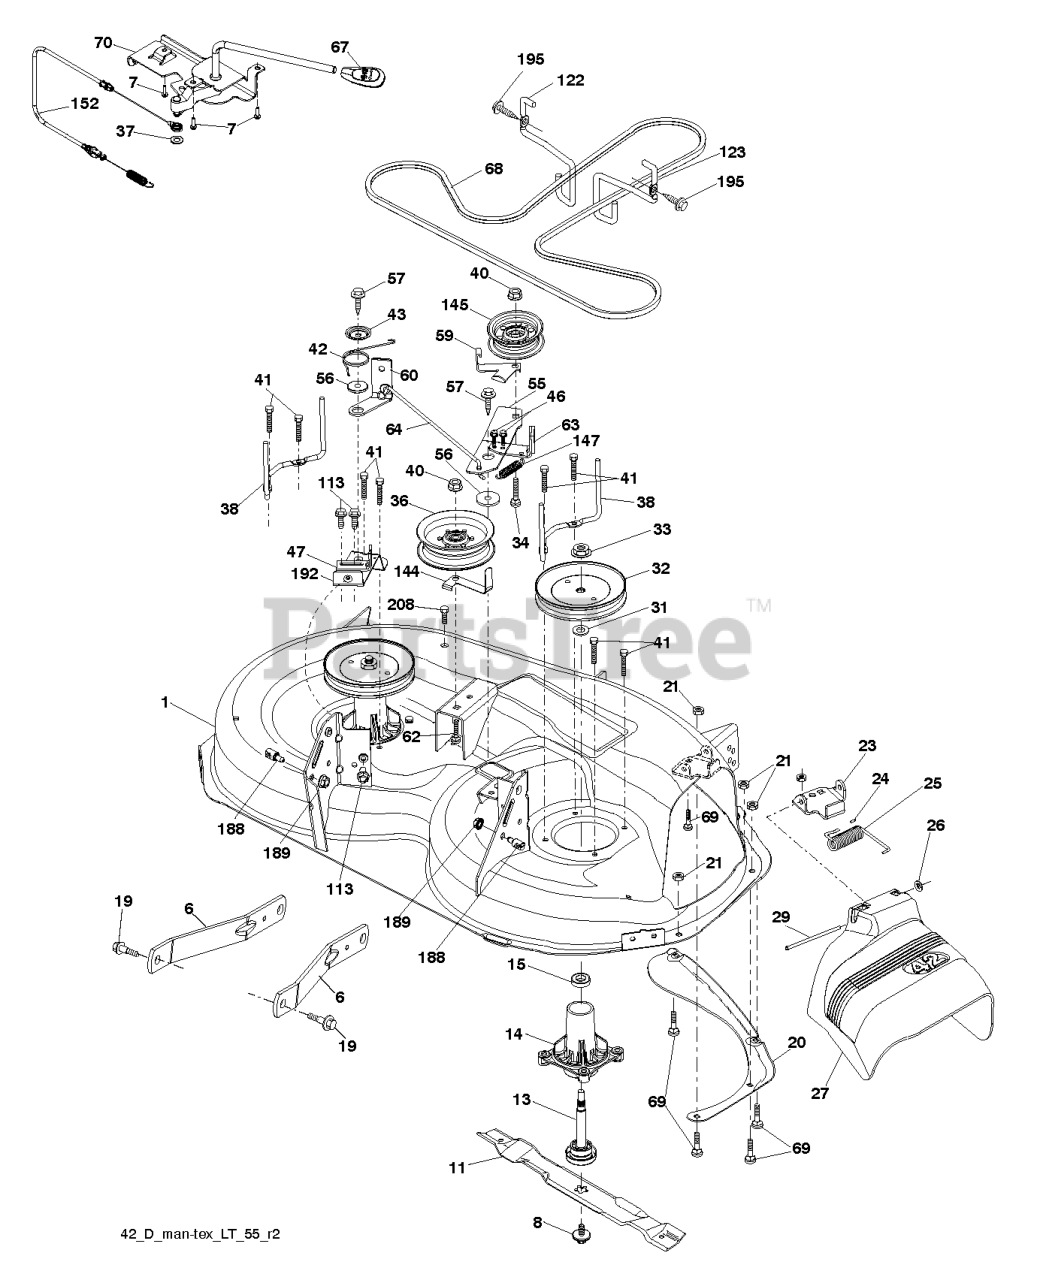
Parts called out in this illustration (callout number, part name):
6	ARM.SUSPENSION.MOWER.R
7	SCREW.#10 X 0.750.BOS (2 2)
8	BOLT.WASHER.ASM.7/16-2
11	42" HI-LIFT BLADE
13	SHAFT.ASM.MDRL.N/GREASE.38
14	HOUSING.MANDREL.4PT.
19	BOLT.SHOULDER
20	BAFFLE.VORTEX
21	LOCKNUT
23	BRKT.DEFLECTOR.38"2005+
24	CAP-SLEEVE LT
25	SPRING.TORSION.DEFLECT
26	NUT PUSH M
27	SHIELD.DEFLECTOR.MOWER.42"BLAC
29	ROD.HINGE
31	WASHER.SPACER.MANDREL
32	PULLEY.MANDREL.5.438.PD
33	NUT.FLANGE.LOCK.TOP
34	BOLT.3/8-16X1.50
36	PULLEY.IDLER.2006
38	KEEPER.BELT.MANDREL.PULLEY
40	NUT LOCK FLG 3/8-16 UNC
41	Hex Washer Head Bolt, .313-18 X 1.19
42	SPRING.TORSION.BRAKE
43	SRPING.TORSION.RETAINE
46	SCREW.1/4-20X5/8
47	BRKT.CLUTCH.CABLE
55	IDLER.ARM.42"
56	SPACER.RETAINER
57	SCREW 3/8-16X1
59	GUARD, BELT
60	ARM BRAKE MOWER
62	BOLT
64	LINK BRAKE
67	HANDLE.CLUTCH.CABLE.LT
68	BELT.DECK.DRIVE.42"
69	BOLT
70	CLUTCH.ASM.MANUAL.LT.PRED
113	BOLT.5/16HEX.WHS.HD
122	KEEPER BELT ENGINE LH
123	KEEPER BELT RH
144	KEEPER.BELT.MOWER
145	PULLEY.IDLER.48"PRIMARY
147	RETURN SPRING
152	CABLE.MECHANICAL.CLUTCH
188	STUD.FASTNER.W/ANTI-ROTATE
189	NUT LOCK HEX FLANGE 5/16-18
192	BRKT.BRAKE.STAND.LH.
195	SCREW, 3/8-16X3/4
208	SCREW 3/8-16X1/2
